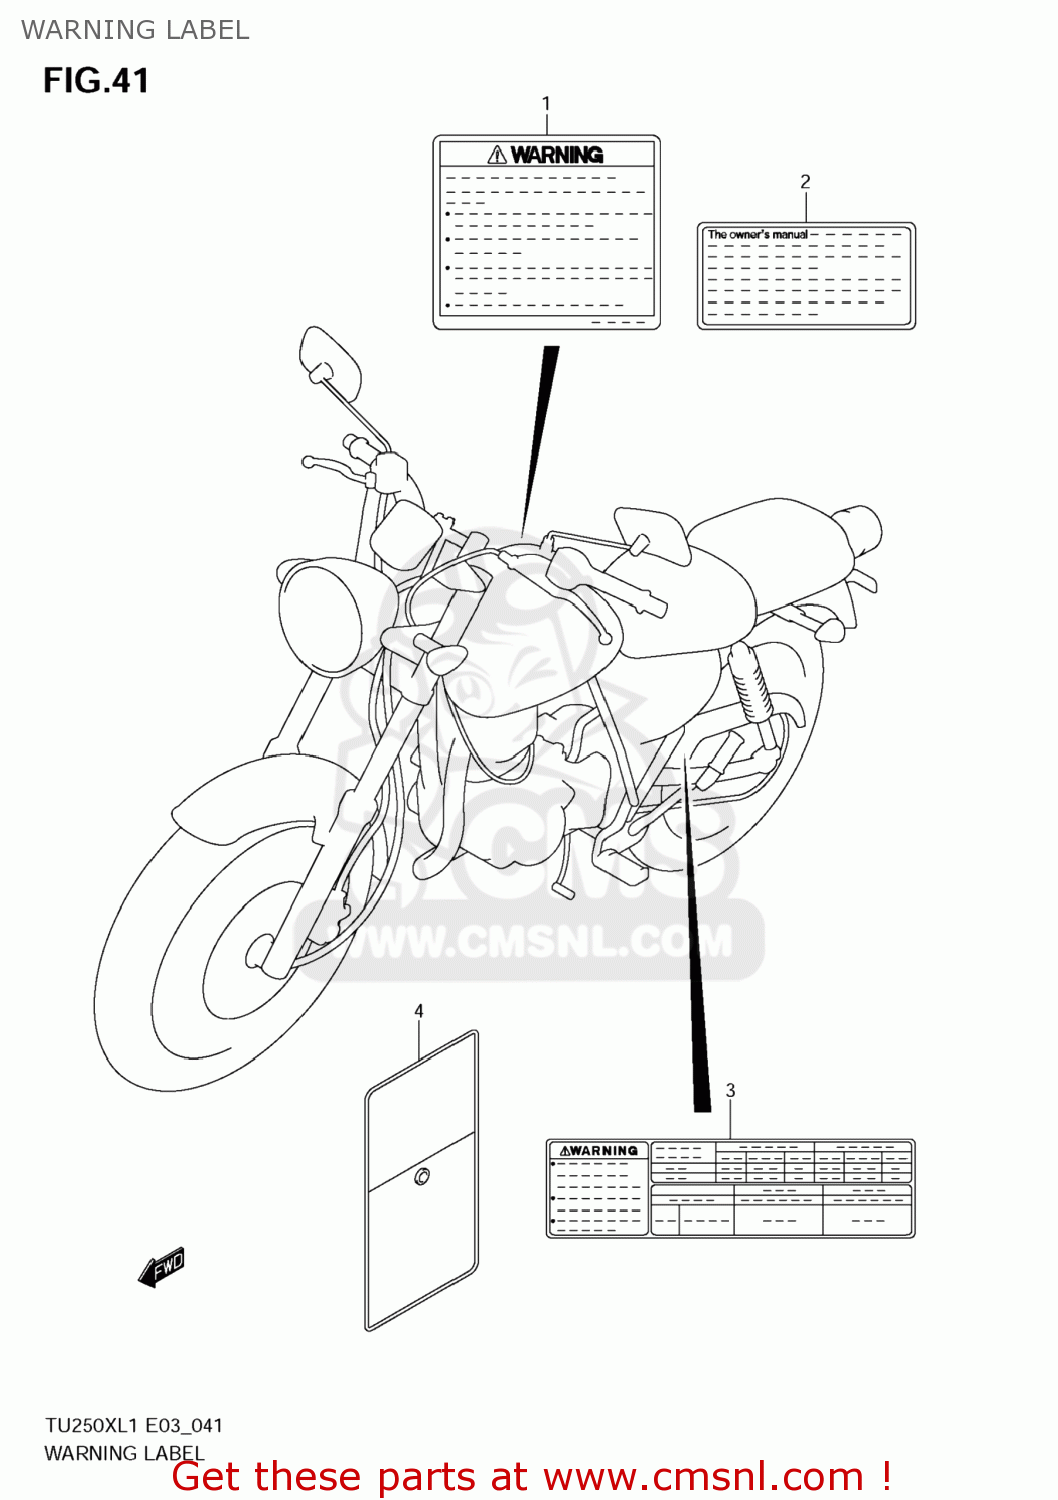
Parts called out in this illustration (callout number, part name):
1	LABEL,GENERAL WARNING
2	LABEL,MANUAL NOTICE
3	LABEL,TIRE INFORMATION
4	BAG,OWNERS MANUAL
5	MANUAL,OWNER'S
